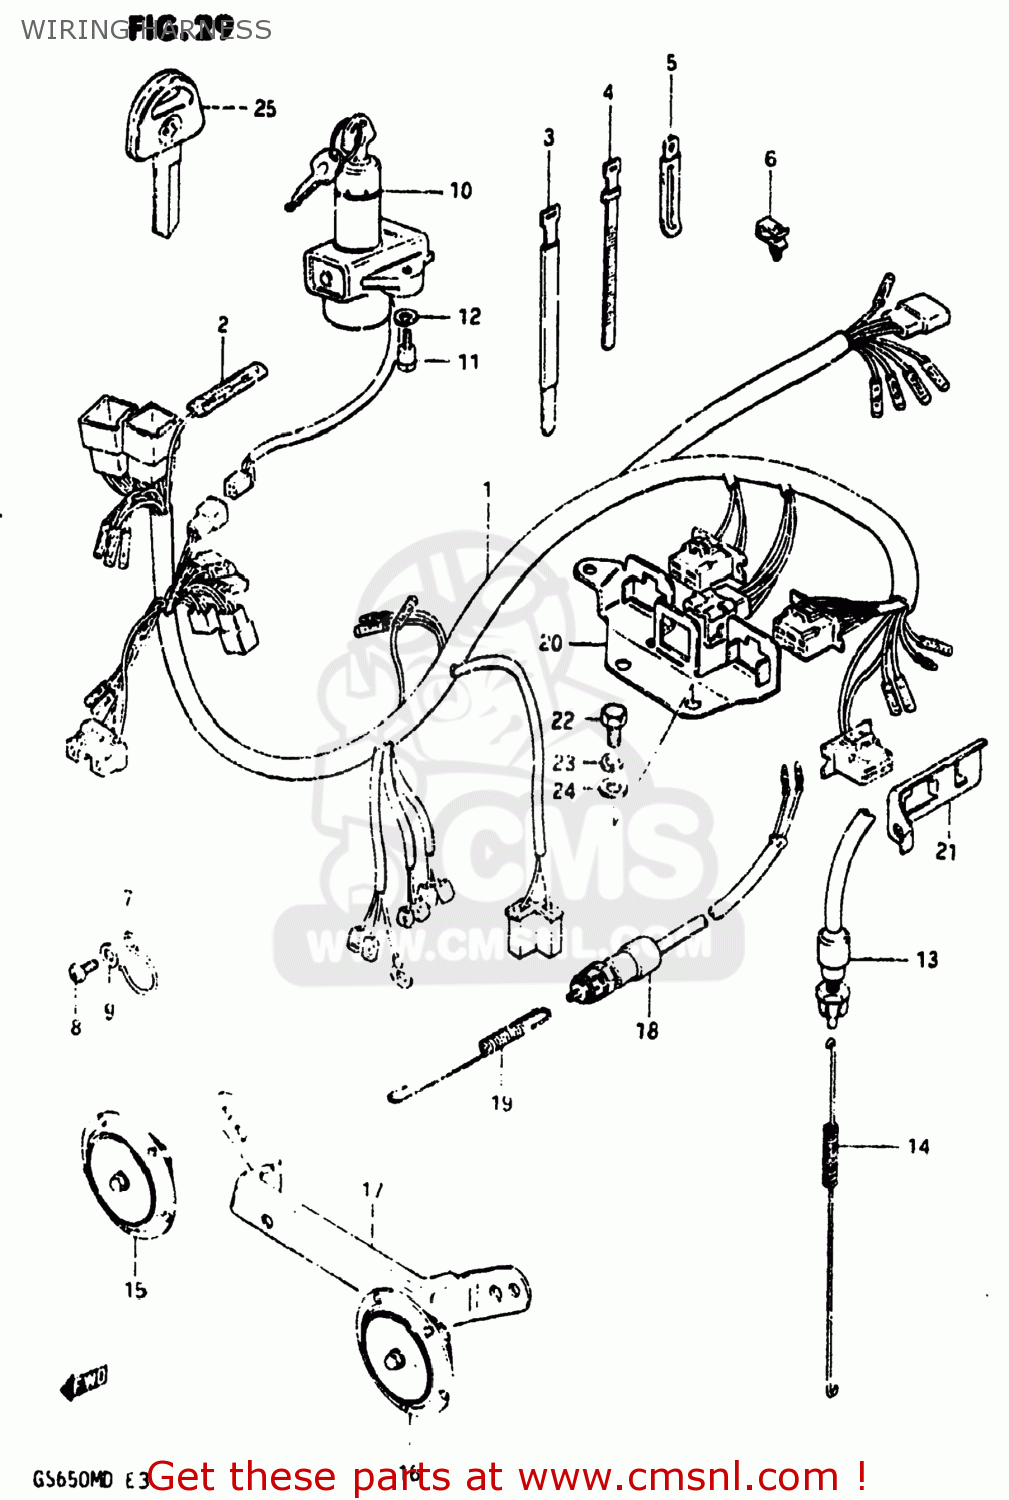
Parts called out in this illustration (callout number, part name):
1	HARNESS,WIRING
2	DIODE
3	CLAMP
4	CLAMP
5	CLAMP
6	CLIP
7	GUIDE,WIRING HARNESS
8	SCREW 6X12
9	WASHER
10	LOCK ASSEMBLY,STEERING
11	BOLT
12	LOCK WASHER
13	SWITCH ASSEMBLY,STOP LAMP
14	SPRING
15	HORN ASSEMBLY,HIGH PITCH
16	HORN ASSEMBLY,LOW PITCH
17	BRACKET,HORN
18	SWITCH ASSEMBLY,SIDE STAND
19	SPRING
20	PLATE, COUPLER HOLDER (A)
21	PLATE, COUPLER HOLDER (B)
22	BOLT
23	LOCK WASHER
24	WASHER
25	KEY,BLANK
